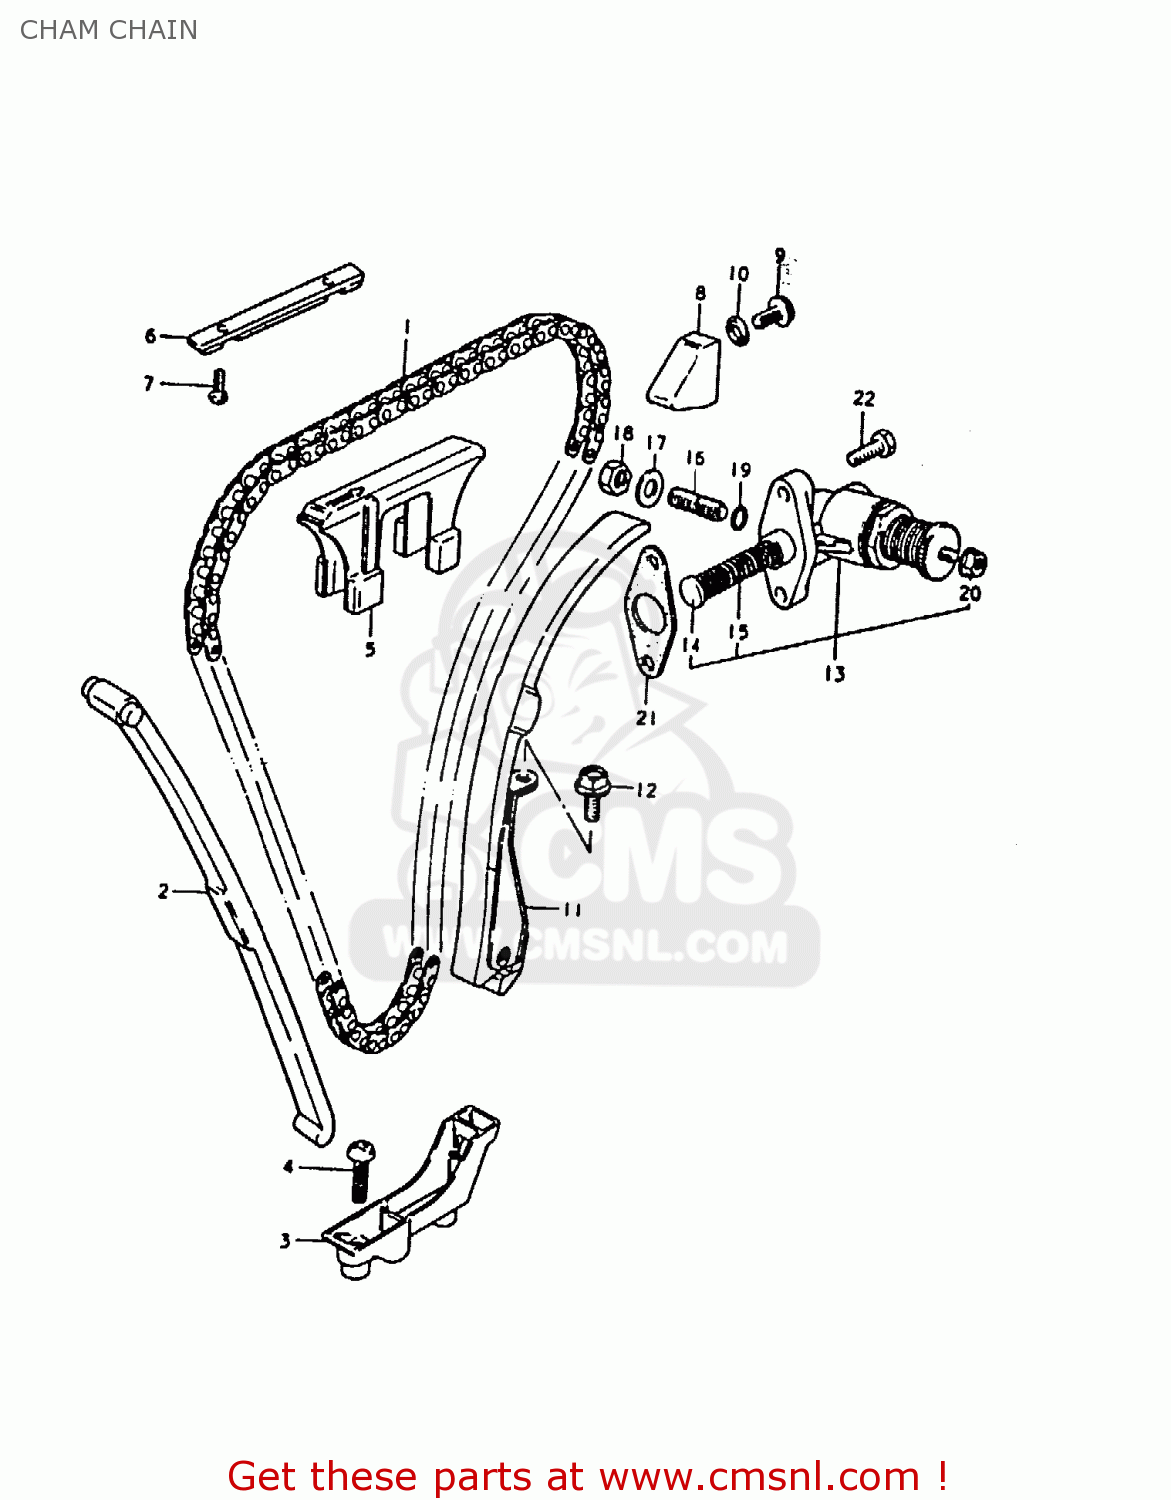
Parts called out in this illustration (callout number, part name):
1	CHAIN,CAMSHAFT DRIVE
2	GUIDE,CAM CHAIN NO.1
3	HOLDER,CAM CHAIN GUIDE
4	SCREW
5	GUIDE,CAM CHAIN NO.2
6	GUIDE,CAM CHAIN
7	SCREW
8	GUIDE,CAM CHAIN
9	BOLT
10	GASKET (NAS)
11	TENSIONER,CAM CHAIN
12	BOLT
13	ADJUSTER ASSY, TENSIONER
14	ROD,PUSH
15	SPRING
16	SCREW
17	WASHER
18	NUT
19	O-RING
20	NUT
21	GASKET,TENSIONER ADJUSTER (MCA)
22	SCREW (6X25)
